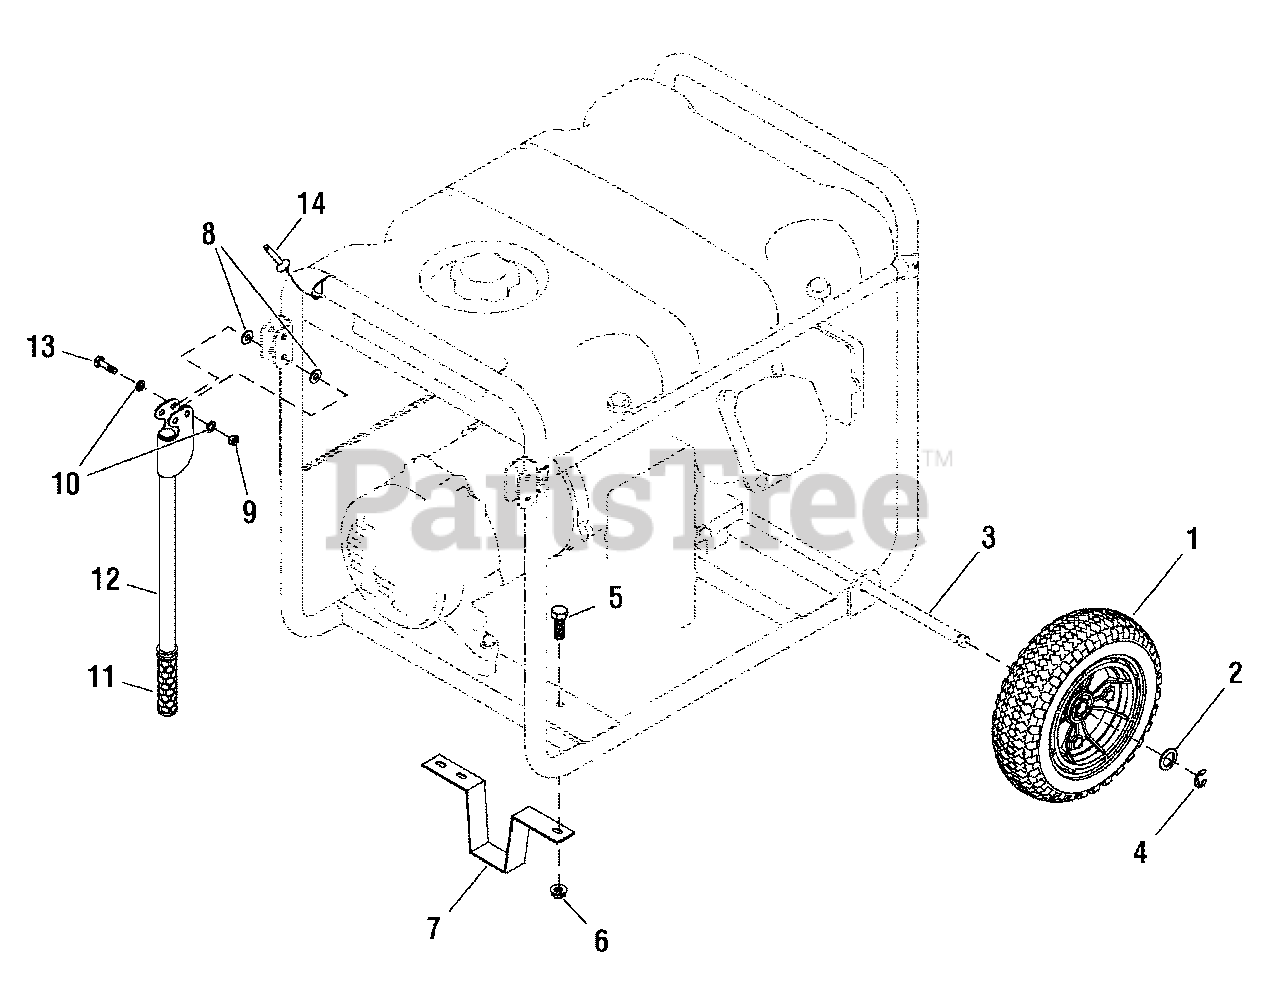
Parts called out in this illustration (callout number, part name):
2	* WASHER, 5/8
4	E-RING
5	* CAPSCREW, Hex Head, M8 - 1.25 x 20
8	* WASHER, Nylon, 1.2 x .346 x .03
9	* NUT, Nylock, M8 x 1-1/4
10	* WASHER, Flat, 5/16-M8
13	* CAPSCREW, Hex Head, M8 - 1.25 x 45
